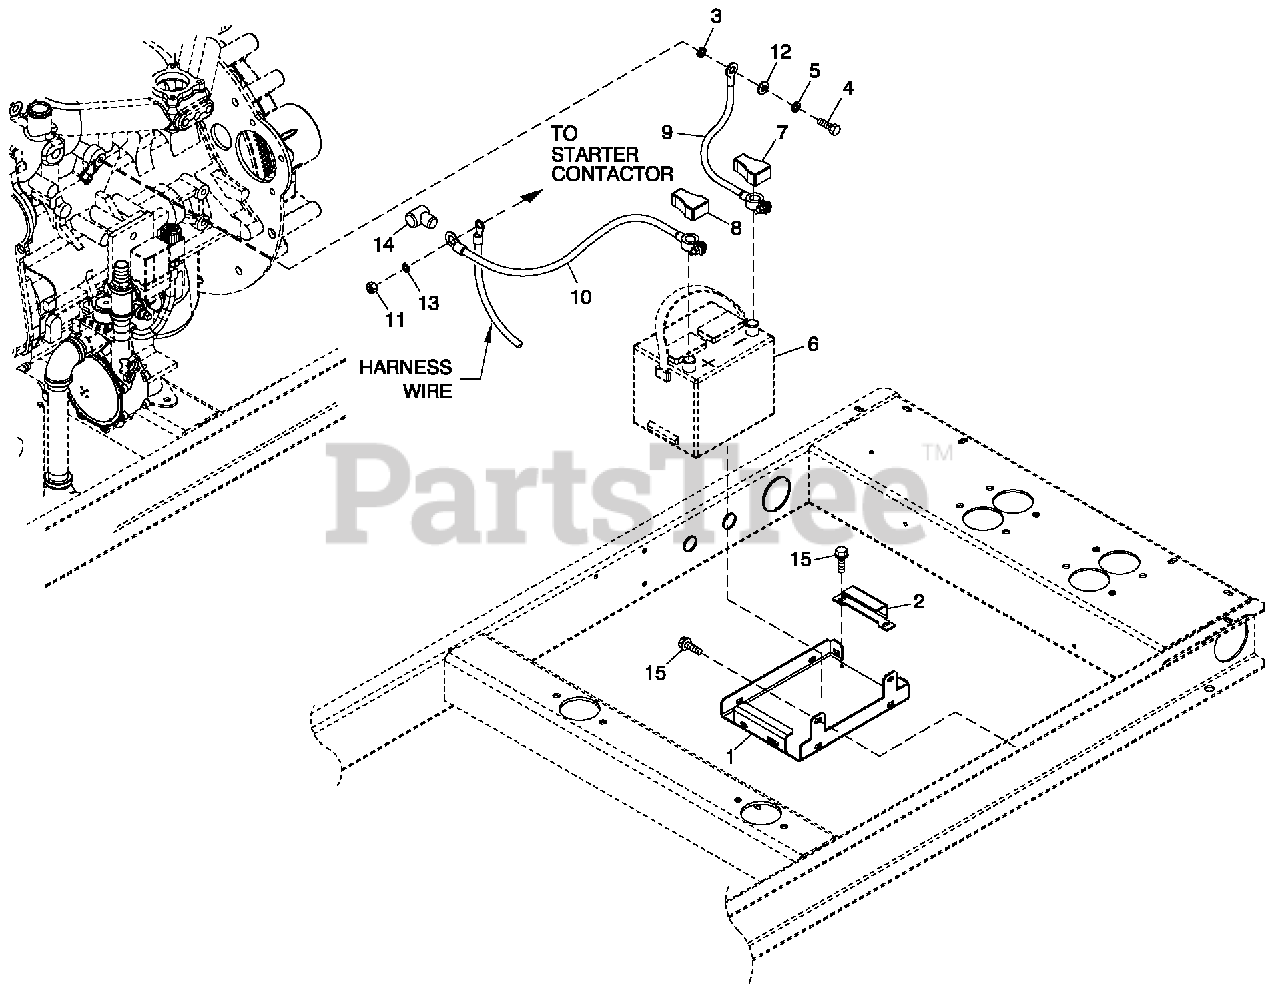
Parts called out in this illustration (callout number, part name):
1	BATTERY TRAY, C1&C2
2	STRAP BATTERY RETAINMENT
3	WASHER SHAKEPROOF EXT 7/16 STL
4	SCREW HHC M10-1.25 X 25 C8.8
5	WASHER LOCK M10
6	BATTERY 12VDC 75-AH 26 (SO LD AS AN OPTION)
7	BATTERY POST COVER RED +
8	BATTERY POST COVER B LK -
9	CAB LE BATTERY B LACK #1 X 30.00
10	CAB LE BATTERY RED #1 X 21.00
11	NUTHEXM8-1.25 G8 YE L CHR
12	WASHER FLAT 3/8-M10 ZINC
13	WASHER SHAKEPROOF EXT 5/16 STL
14	BOOT CONTACTOR CAB LES
15	SCREW THF M6-1 X 16 N WA Z/JS
